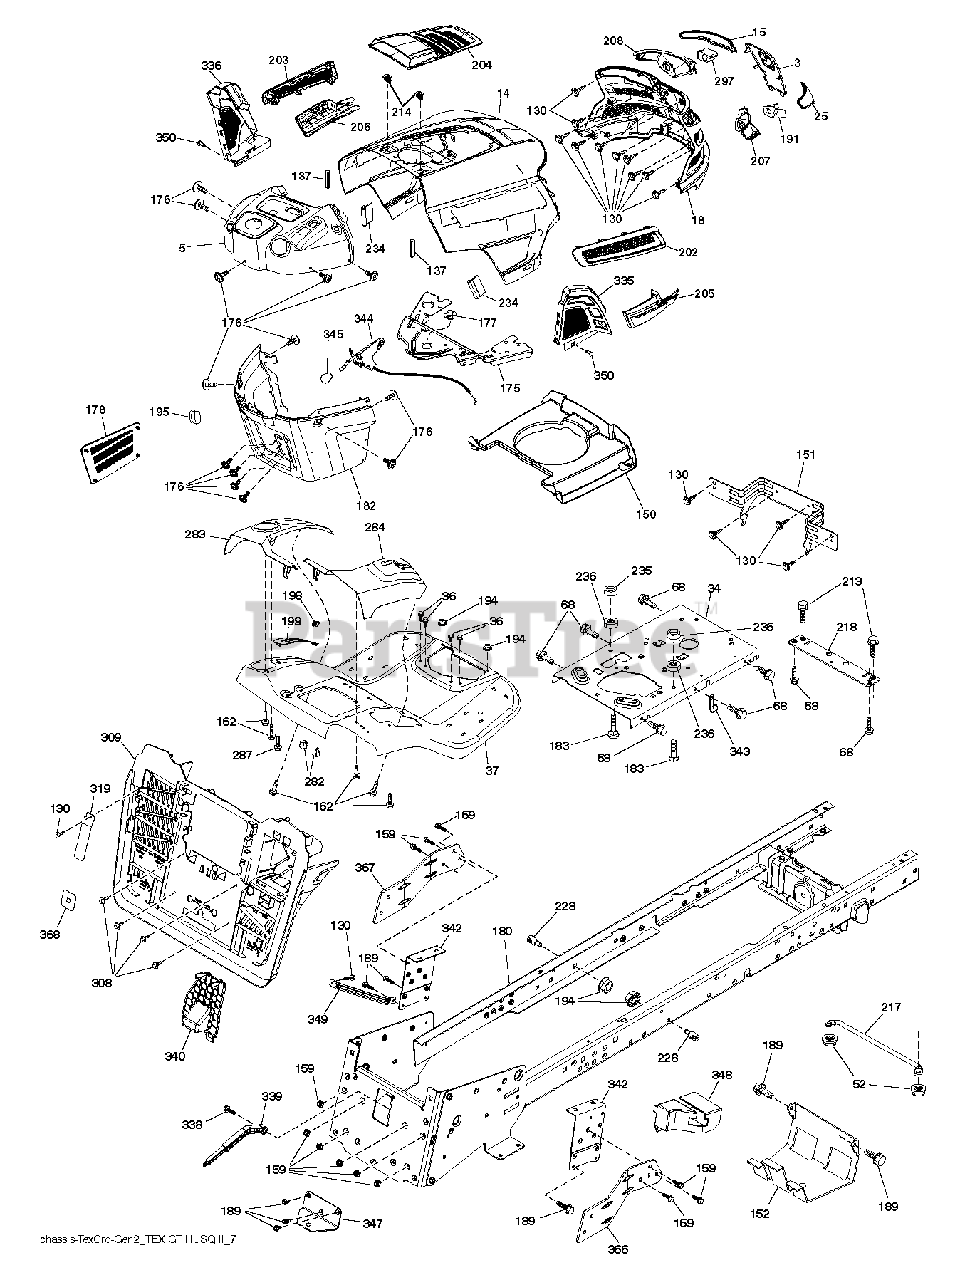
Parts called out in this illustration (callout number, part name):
3	APPLIQUE.SUBASM.GT.HUSQ.II
14	HOOD.ASM.HUSQVARNA.GT.TEX.ORAN
15	LENS.HEADLIGHT.LH.GTII.2011
18	GRILLE.SUBASM.GT.HUSQ.II
25	LENS.HEADLIGHT.RH.GTII.2011
34	PLATE.ENGINE.WELDED.CHASSIS
36	SCREW 5/16"
37	FENDER.TEX.SRD.CRD.FRN.GUARDS
52	LOCKNUT
68	SCREW LT
130	SCREW.#10 X 0.750.BOS
137	BUMPER DASH
150	AIR DUCT.GTV2(1.66"RING HEIGHT
151	BRACKET.PIVOT.HOOD.GT.HUSQ.II
152	SHIELD.BROWNING.PNT.GT.V2
159	SCREW, 3/8-16X3/4
162	SCREW.HI-LO.CONSOLE
175	PLATE.CROSSMEMBER.HUSQ
176	SCREW.#10-24X5/8.RN.QU
177	BUSHING, STEERING
178	CARGO.ASM.NET.TXGT.W/C
182	DASH DASH LOWER
183	BOLT.5/16-18X1-1/4 FULL THD
189	SCREW
191	INSERT.REFLECTIVE.RH.HUSQ.GTII
194	NUT LOCK HEX FLANGE 5/16-18
195	PLUG.HOLE.DASH.LOWER.12V.BLK
198	INDICATOR.DECK.LIFT.RED
199	PLATE DECK LIFT
202	VENT.SIDE.RH.GT.HUSQ.II.
203	VENT.SIDE.LH.GT.HUSQ.II.498
204	VENT.TOP.EXTERNAL.FILL.GT2.GRE
205	SIDE.TRIM.RH.GT.HUSQ.II
206	SIDE.TRIM.LH.GT.HUSQ.II.GRAY
207	BEZEL LIGHT.RH.GT.II.MYLAR
208	BEZEL LIGHT.LH.GT.II.MYLAR
213	BOLT
214	CLIP.RETAINER.TINNER.
217	ROD.PIVOT.HOOD
218	X-PIECE.HOOD.STOP.NON/
228	STUD.FASTNER.W/ANTI-ROTATE
234	BUMPER.HOOD.TEX.HUSQVARNA
235	SPACER FENDER
236	NUT.CENTERLOCK.5/16-
282	CLIP.RETAINER.CONSOLE.LT.HUSQ
283	CONSOLE.DECKLIFT.CRDII.498
284	CONSOLE.PEDAL.HYDRO
287	SCREW 1/4X20
297	INSERT.REFLECTIVE.LH.HUSQ.GTII
308	BOLT, 5/16-18 X 1 3/4
309	BACKPLATE.SUBASM.SERV.TEX.CRD.
319	LEVER.BAGGER.TEX.CRD.GEN.BLACK
335	COVER.LOWER.DASH.RH.BLACK
336	COVER-LH.LOWER.DASH.GT2.BLACK
338	BOLT BOLT SHOULDER
339	LEVER LEVER BAGGER
340	BATTERY.DOOR.TEX.CRD.GEN.2,1
342	SUPPORT SUPPORT FENDER
343	CLIP CLIP
344	CONTROL.EZ.MULCH.TEX/CRD
345	RP KNOB.OVAL.TAPERED.3/8-16BLK
347	HITCH TOW
349	BRACKET.SUPPORT.LRVB/CRD
350	CLIP.X-MAS.TREE
366	BRACKET.RH.FRONT.BAGGER.BLACK
367	BRACKET.LH.FRONT.BAGGER.BLACK
368	FULL.LEVER.BAGGER.TEX.CRD
